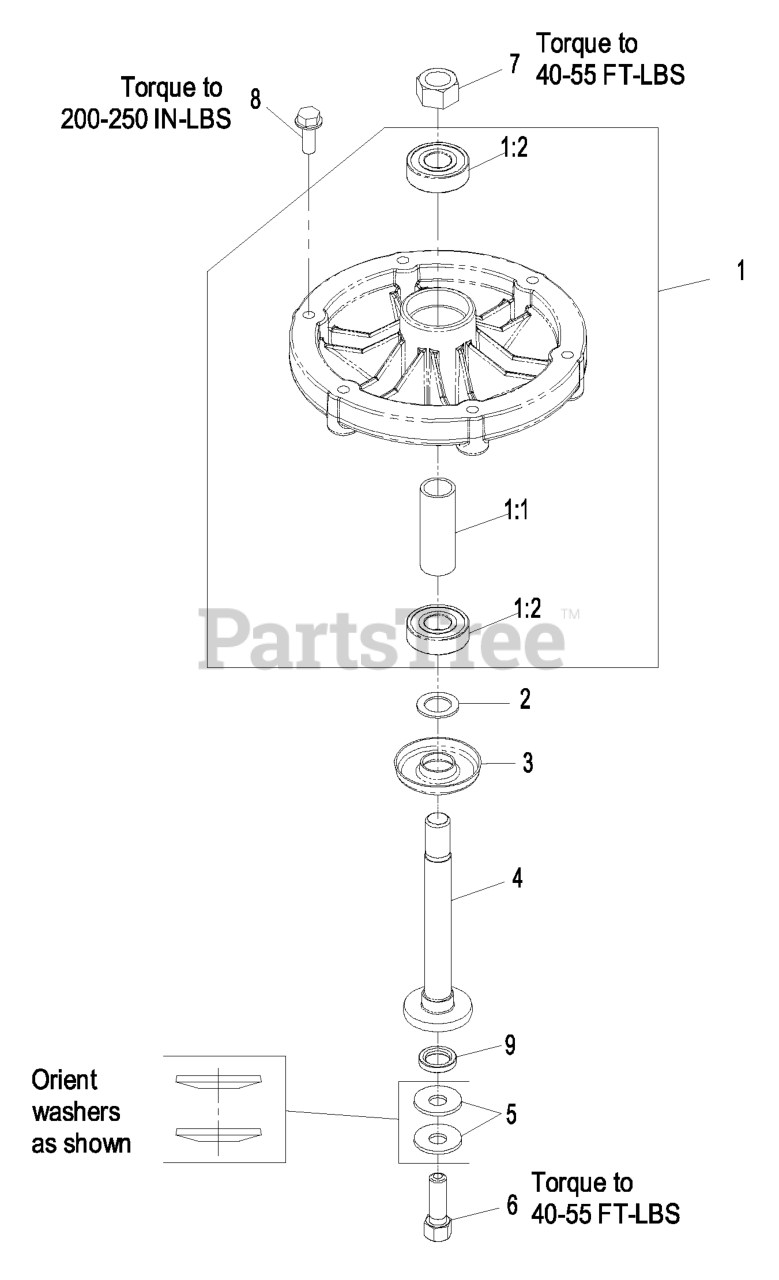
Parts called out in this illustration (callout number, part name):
3	SHIELD-BEARING
4	SHAFT-SPINDLE
5	WASHER-BELLEVILLE
6	SCREW-HH
7	NUT-HEX
8	SCREW-TAPTITE
